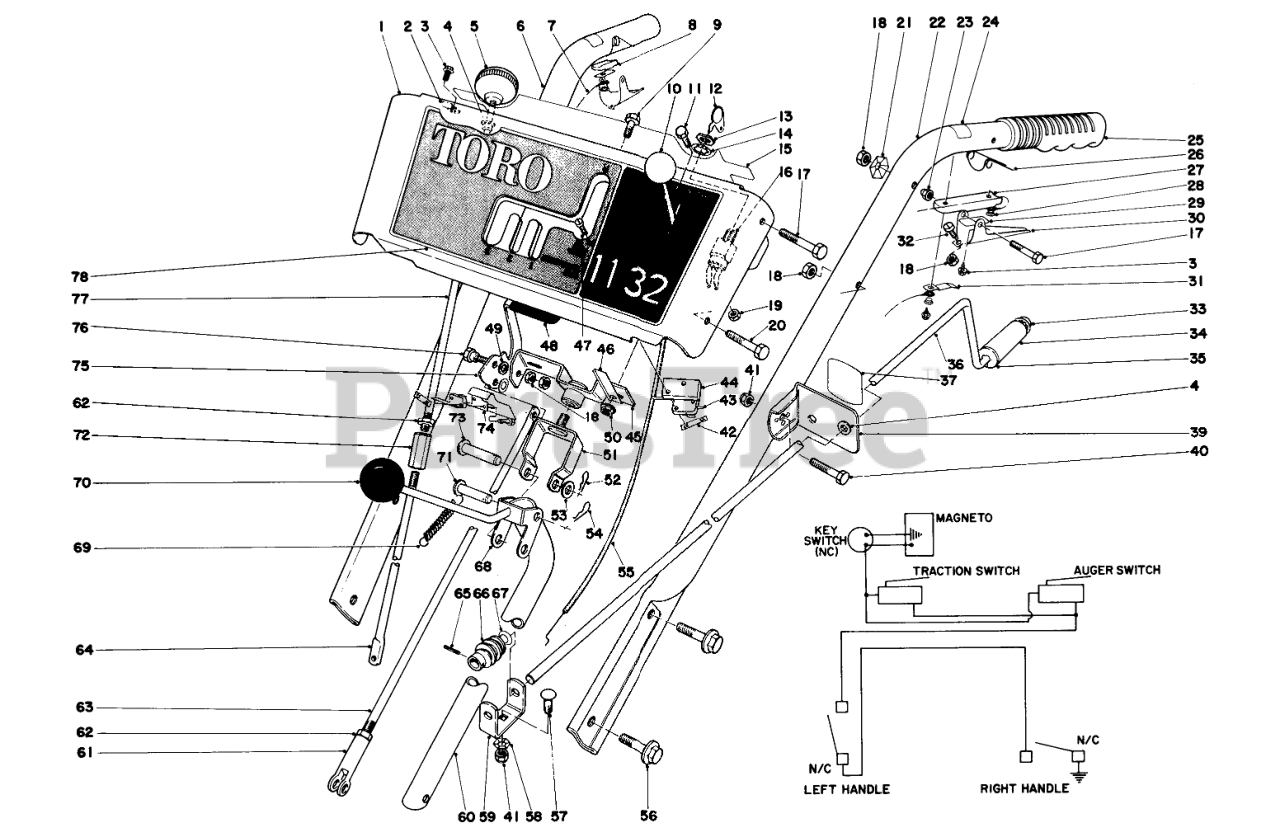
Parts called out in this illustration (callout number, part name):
1	Escutcheon Plate (Incl. Ref. #15 & 78) (Model #38090)
2	PLASTIC CLIP
3	SCREW
4	Bushing
5	KNOB-LEVER
6	Handle Right
7	Wire Harness
8	Insulator
9	SCREW-HH
10	CONTROL KNOB
11	HEX HEAD SEMS 10-24X1/2
12	Key
13	NUT-HH
14	WASHER-TOOTH, INTERNAL
15	BACK ESCUTCH DECAL
16	SWITCH-ON / OFF
17	SCREW-HH
18	NUT-LOCK, CONE
19	Nut
20	SCREW-HH
21	Washer
22	LEFT HANDLE
23	NUT-CAP
24	INTERLOCK DECAL
25	Grip Handle
26	INTERLOCK SPRING
27	DUAL BRKT INSULATOR
28	WASHER INSULATOR
29	INTERLOCK CONTACT
30	SAFETY INTRLOCK LEVER
31	CONTACT BRACKET
32	NYLON SCREW 1/4 20
33	RETAINER-PUSH ON
34	CHUTE CONTROL GRIP
35	WASHER-FLAT
36	ROD CHUTE CONTROL
37	CHUTE DECAL
39	Bracket Chute Control Mounting (Incl. Ref. 41 & 37)
40	SCREW-HH
41	NUT-LOCK, NI
42	NUT-SPEED
43	MICRO SWITCH
44	SWITCH MTG PAD
45	SWIVEL BLOCK WA
46	Retainer Wire
47	SCREW-SPH
48	AUGER CLUTCH HND GRIP
49	WASHER-PLAIN
50	NUT-LOCK, HHF
51	PIVOT BRKT WA
52	PIN-HAIR
53	WASHER-FLAT
54	PIN-COTTER
55	Throttle Contrl
56	SCREW-HHF
57	BOLT-CARR
58	WASHER-LOCK
59	WORM BRACKET
60	Rod Traction Shift
61	Clevis
62	NUT-HJ
63	DRAG LINK
64	LOWER WHL CLUTCH ROD
65	PIN-SPRING
66	GEAR-WORM, CHUTE
67	WASHER-SPRING
68	SHIFT ROD WA
69	CONT ROD SPRING 0
71	PIN-CLEVIS
72	WHL ROD COUPLING
73	PIN-CLEVIS
74	SWITCH BRKT
75	Auger Clutch Handle
76	SCREW-SHOULDER
77	UP WHEEL CLUTCH ROD
78	Decal Escutcheon (Model 38070)
